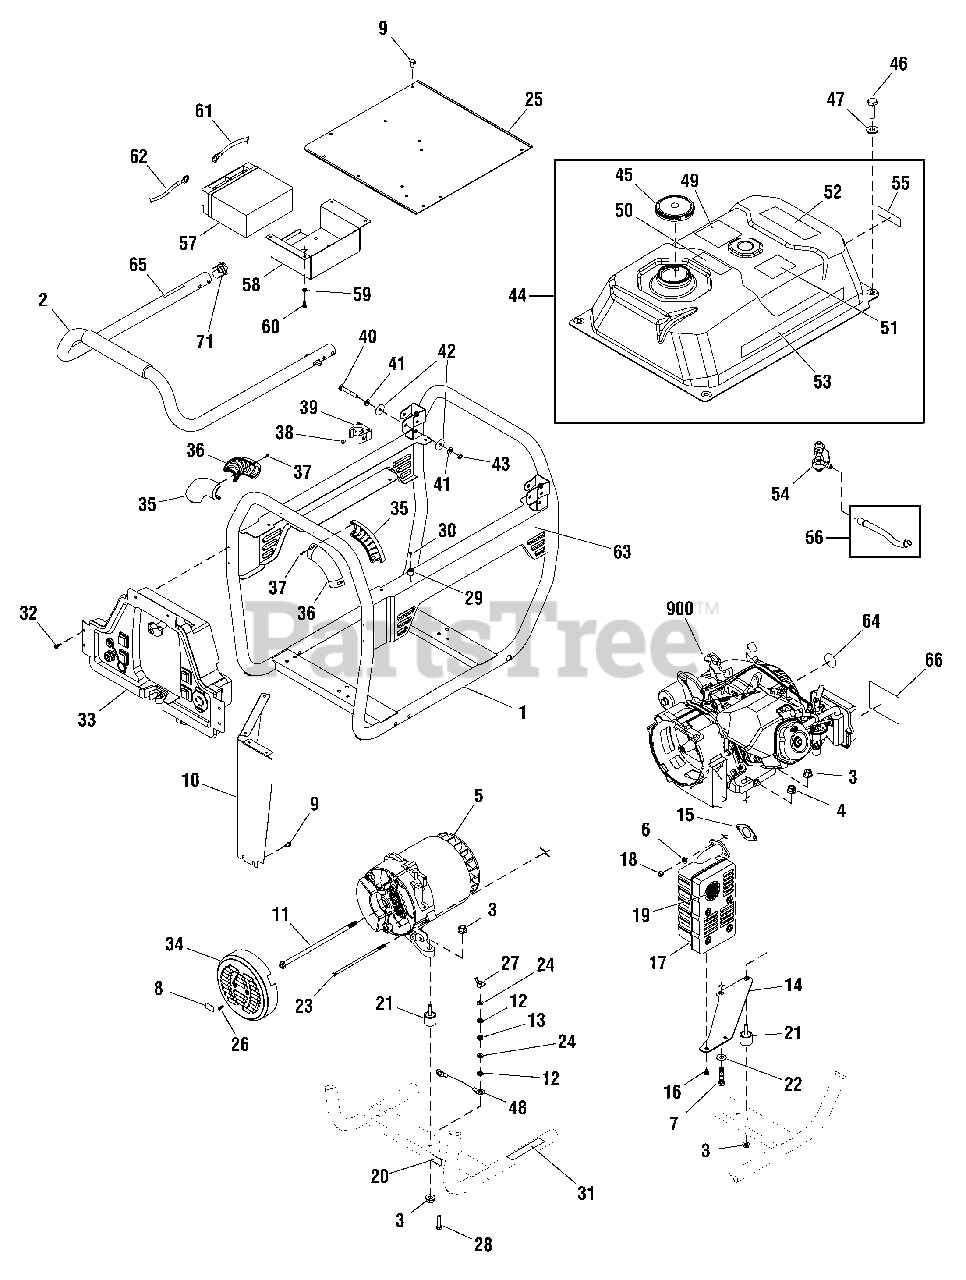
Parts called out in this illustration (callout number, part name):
5	ALTERNATOR
6	* WASHER, Lock, 3/8
7	* CAPSCREW, Hex Head, M10 - 1-1/2 x 45
9	* CAPSCREW, Hex Head, M6-1 x 10
12	* WASHER, Lock, 1/4
13	* NUT, M6-1
15	GASKET, Exhaust
16	* CAPSCREW, Hex Head, M6-1 X 12
18	* NUT, M8 - 1-1/4
21	MOUNT, Vibration
22	WASHER
24	* WASHER, M6
28	* CAPSCREW, Hex Head, M6-1 x 25
34	COVER, Rear Bearing
44	TANK, Fuel
46	* CAPSCREW, Hex Head, M6-1 x 20
47	* WASHER, Flat, 1/4
56	KIT, Fuel Hose
900	** ENGINE
